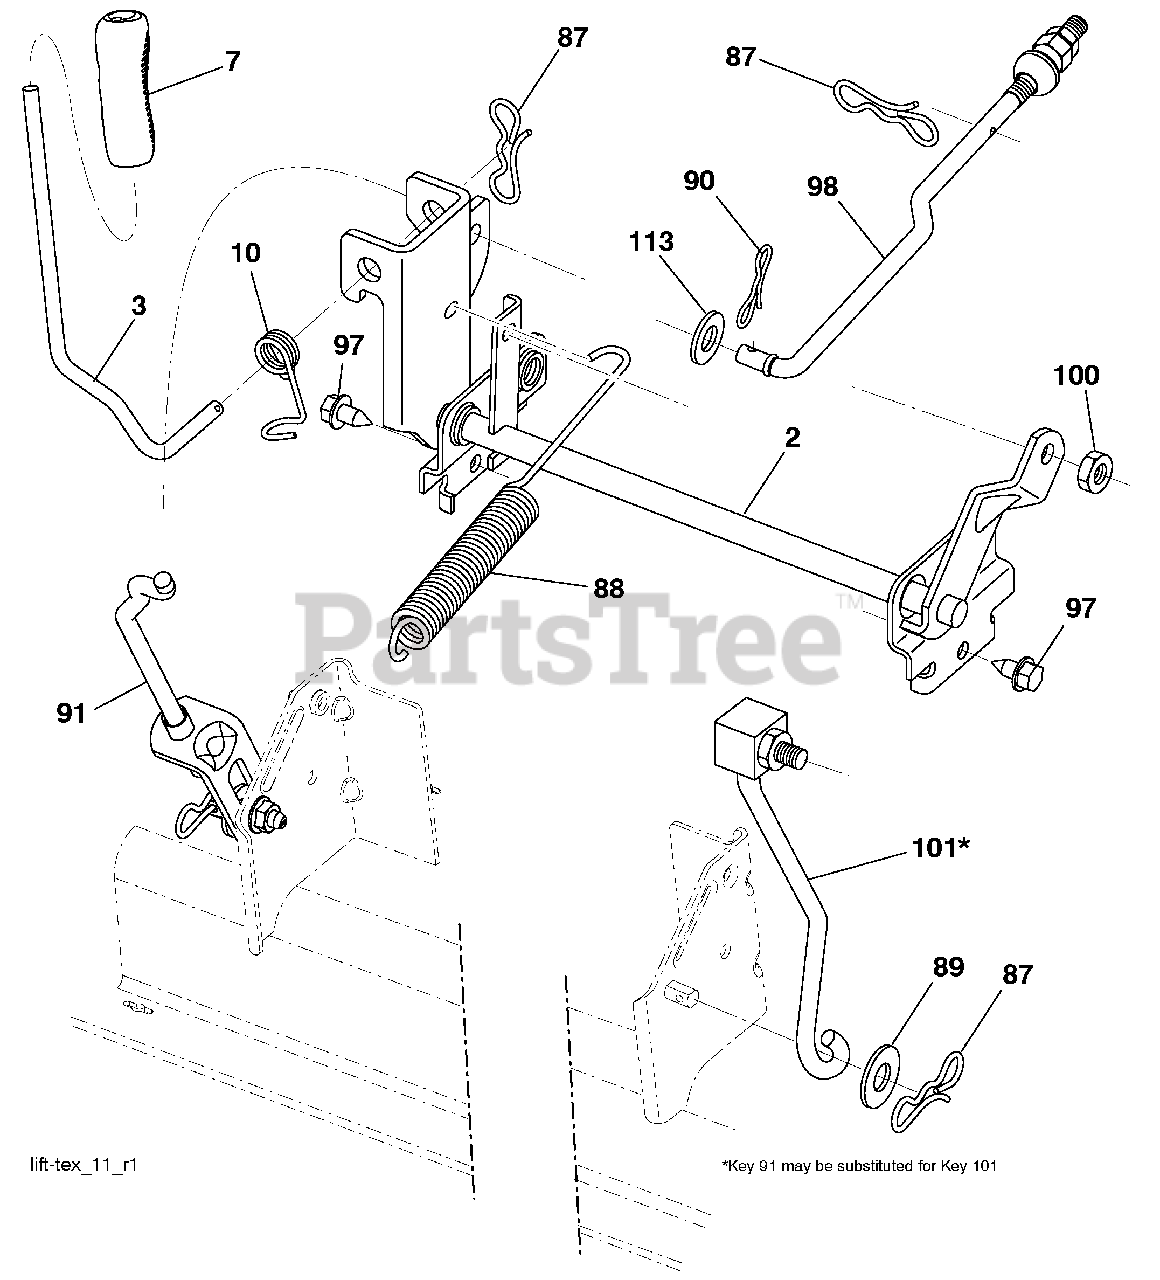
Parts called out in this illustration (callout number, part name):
2	Shaft Asm.,Cross Lift
3	Lever Asm., Lift RH
7	Grip, Lever
10	Spring Torsion
87	Pin Cotter 7/16 Bow Tie Lock
88	Spring Lift Assist
89	Washer Clear Zinc
90	Pin Cotter 5/16 Bow Tie Lock
91	Link Lift Susp Mower Rear
97	Screw 3/8-16 x .75 Smgml Tap/R.Z
98	Link Lift Susp. Front Mower
100	Nut Centerlock 3/8 -16 unc
101	Link Asm Lift Fixed
113	Washer 17/32 x 1-3/16 x 12 Ga.
